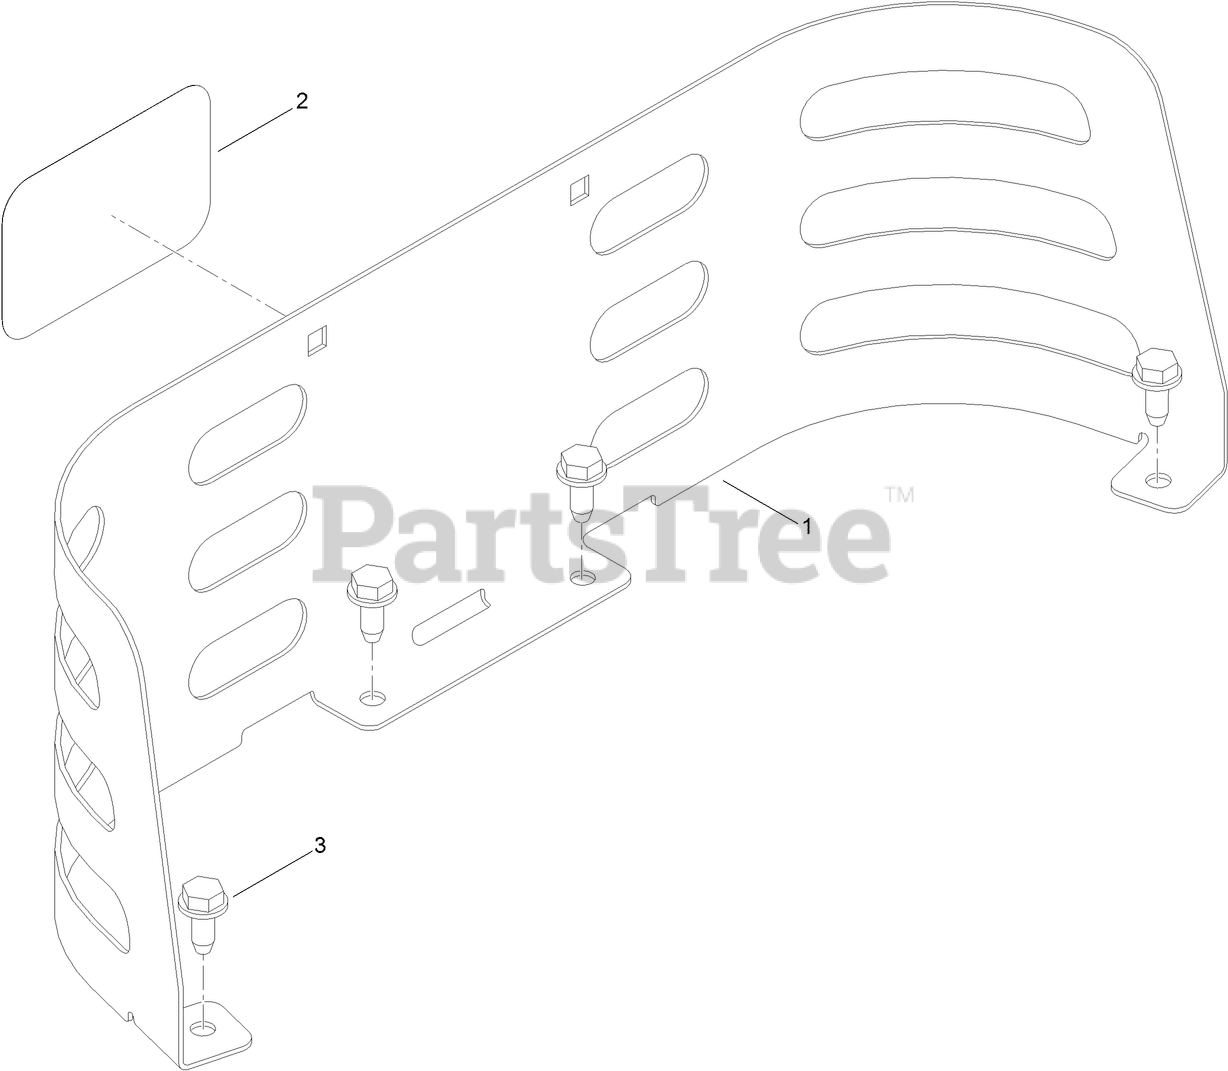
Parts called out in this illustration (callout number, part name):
1	GUARD-REAR
2	DECAL
3	SCREW-HWHTF
